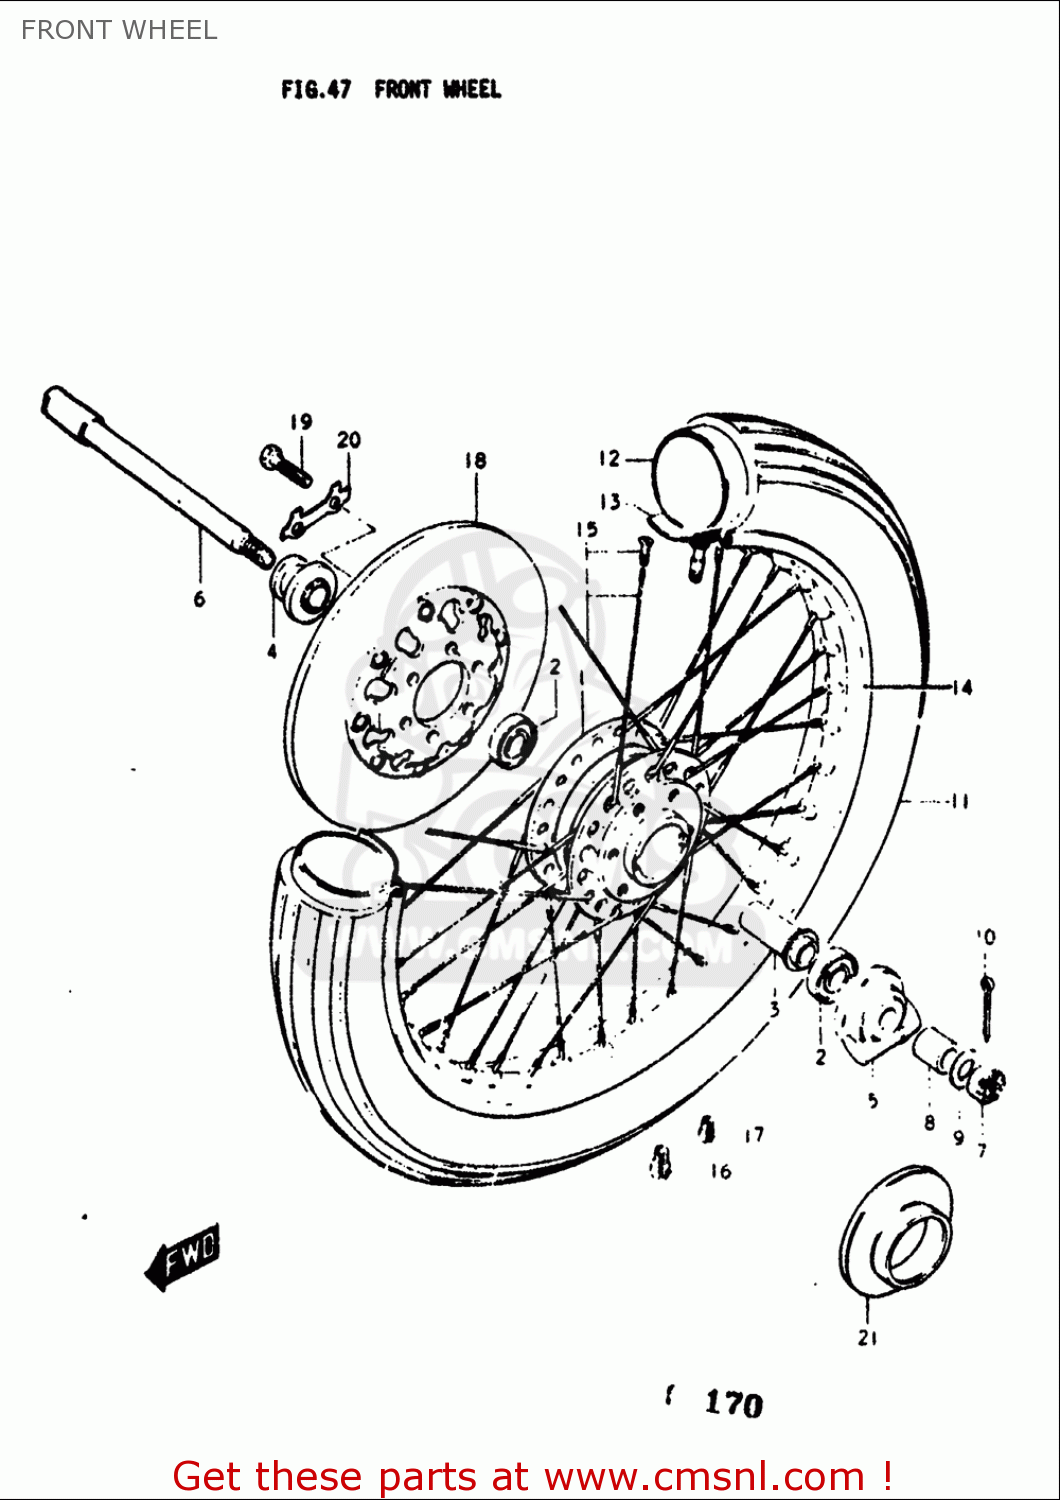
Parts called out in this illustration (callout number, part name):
1	HUB,FRONT WHEEL
3	SPACER,FR HUB BEARING
4	SPACER,FR AXLE,R
5	BOX ASSY,SPEEDOMETER GEAR
6	AXLE,FRONT
7	NUT 12MM
8	SPACER(15X22X30)
9	WASHER
10	PIN
13	PROTECTOR,WHL INR TUBE
15	SPOKE ASSY,FR
16	BALANCER,WHEEL (30G)
17	BALANCER,WHEEL (B)
18	DISC,BRAKE
19	BOLT(8X30)
20	WASHER
